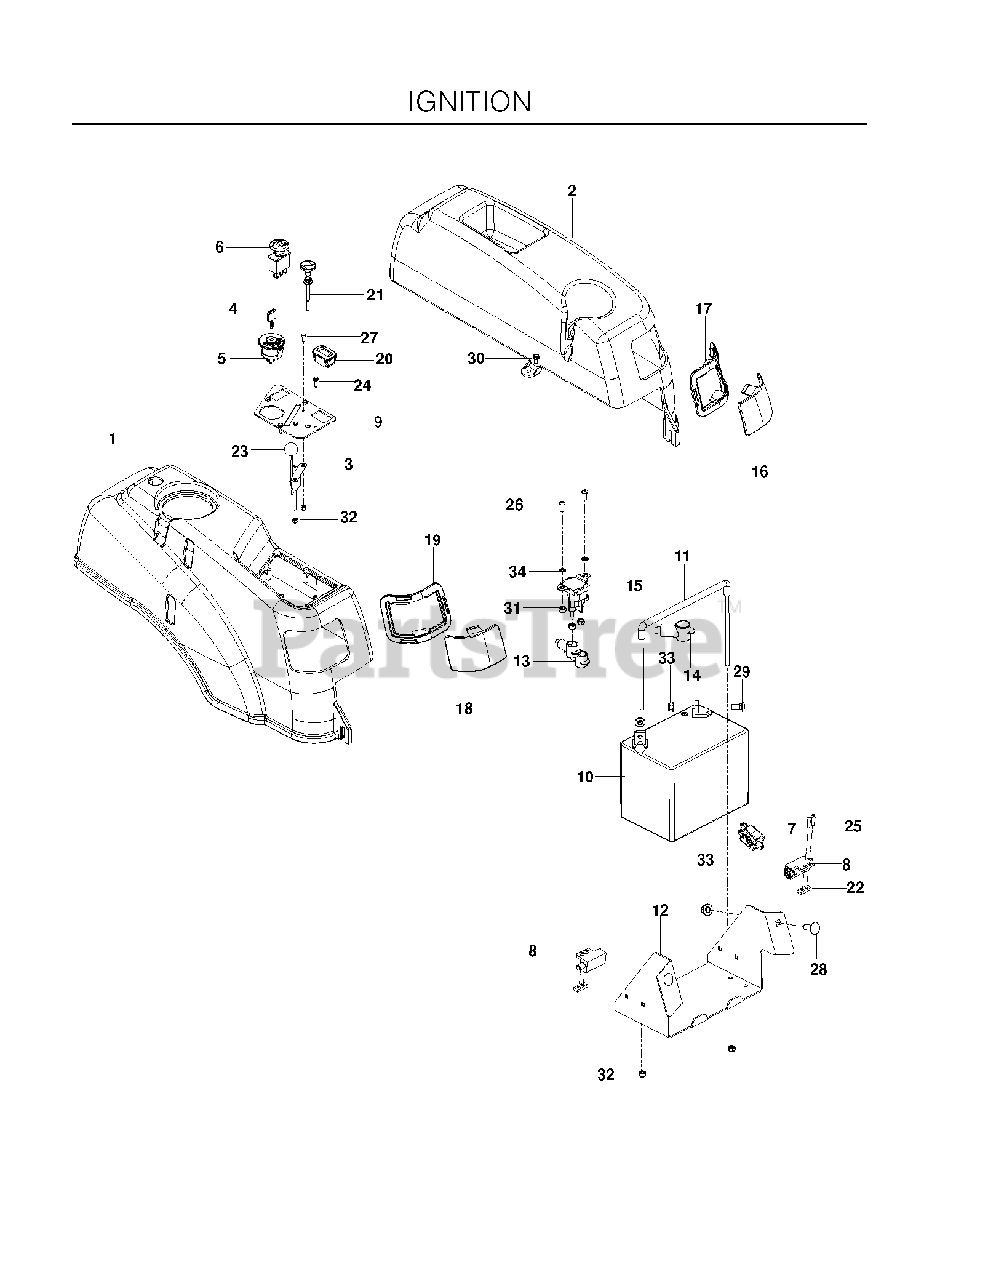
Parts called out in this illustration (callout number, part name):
1	FENDER, LT
2	FENDER, RT, GRAY
3	THROTTLE CABLE
4	KEY MLD GEN DELTA
5	RP IGNITION SWITCH
6	RP SWITCH, BLADE
7	SWITCH, BRAKE 3P
8	SWITCH INTERLOCKT
9	CONSOLE.PLATE.BLACK
10	BATTERY, 12 V 330 AMP
11	BATTERY TIE DOWN ASSEMBLY
12	BOX, BATTERY, BLACK
13	TERMINAL COVER-SM
16	LENS, COLORED LEFT
17	LEFT HEADLIGHT RIM GREY
18	LENS, COLORED RIGHT
19	RT HEADLIGHT RIM GREY
20	HOUR METER
21	CHOKE CABLE
22	TAPPED PLATE
23	KNOB.ROUND.BALL.BLACK
24	HCS #10-24 X 1/2
25	SCR #10-24 X .75 SKT HD BLK
26	SCREW #10 X 1/2 SELF TAPPING
26	SCR 1/4-20 X 5/8 BTN SKT HD ZD
27	SCR #10-12X3/4 HEX WAS HD ZD
28	RHSNB 3/8C X 1
29	BOLT 5/16C X 3/4" CARRIAGE
30	BOLT 1/4-20 X 1/2 HWST
31	RP_NUT 1/4-20 NYLOC
32	NUT 3/8-16 NYLOC
32	NUT 10-24 NYLOC
33	5/16-18 NYLOC FLANGE NUT
34	WASHER 1/4 INT TOOTH
